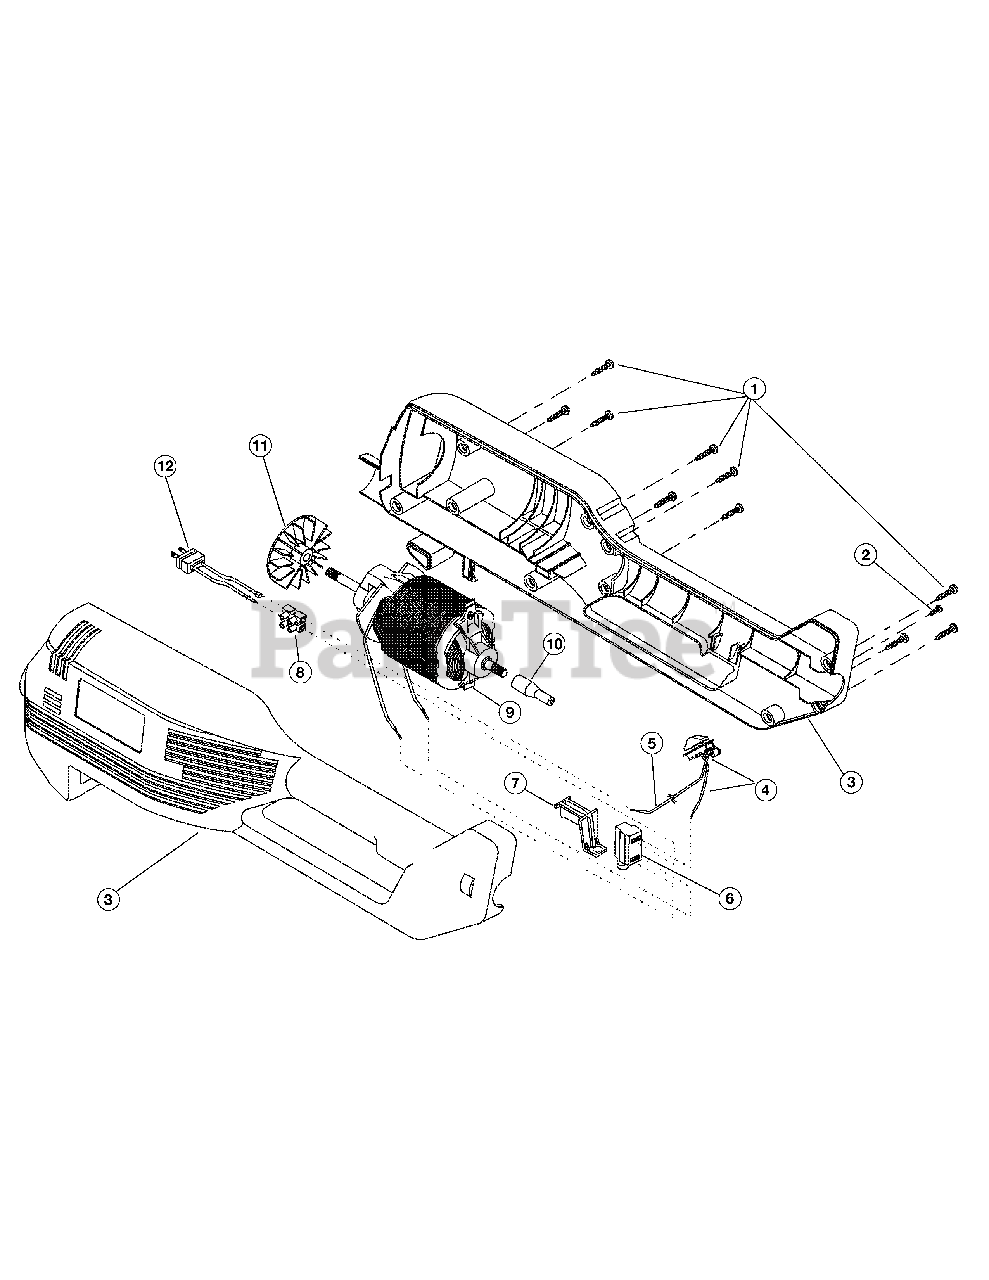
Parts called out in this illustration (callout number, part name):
1	Screw, Housing Set
2	Anti-Rotation Screw
3	Motor Housing Assembly
4	Two-Speed Switch Assembly
5	Lead Wires
7	Trigger
8	Terminal Block
9	Motor Assembly
11	Cooling Fan
12	Recessed Plug Assembly
